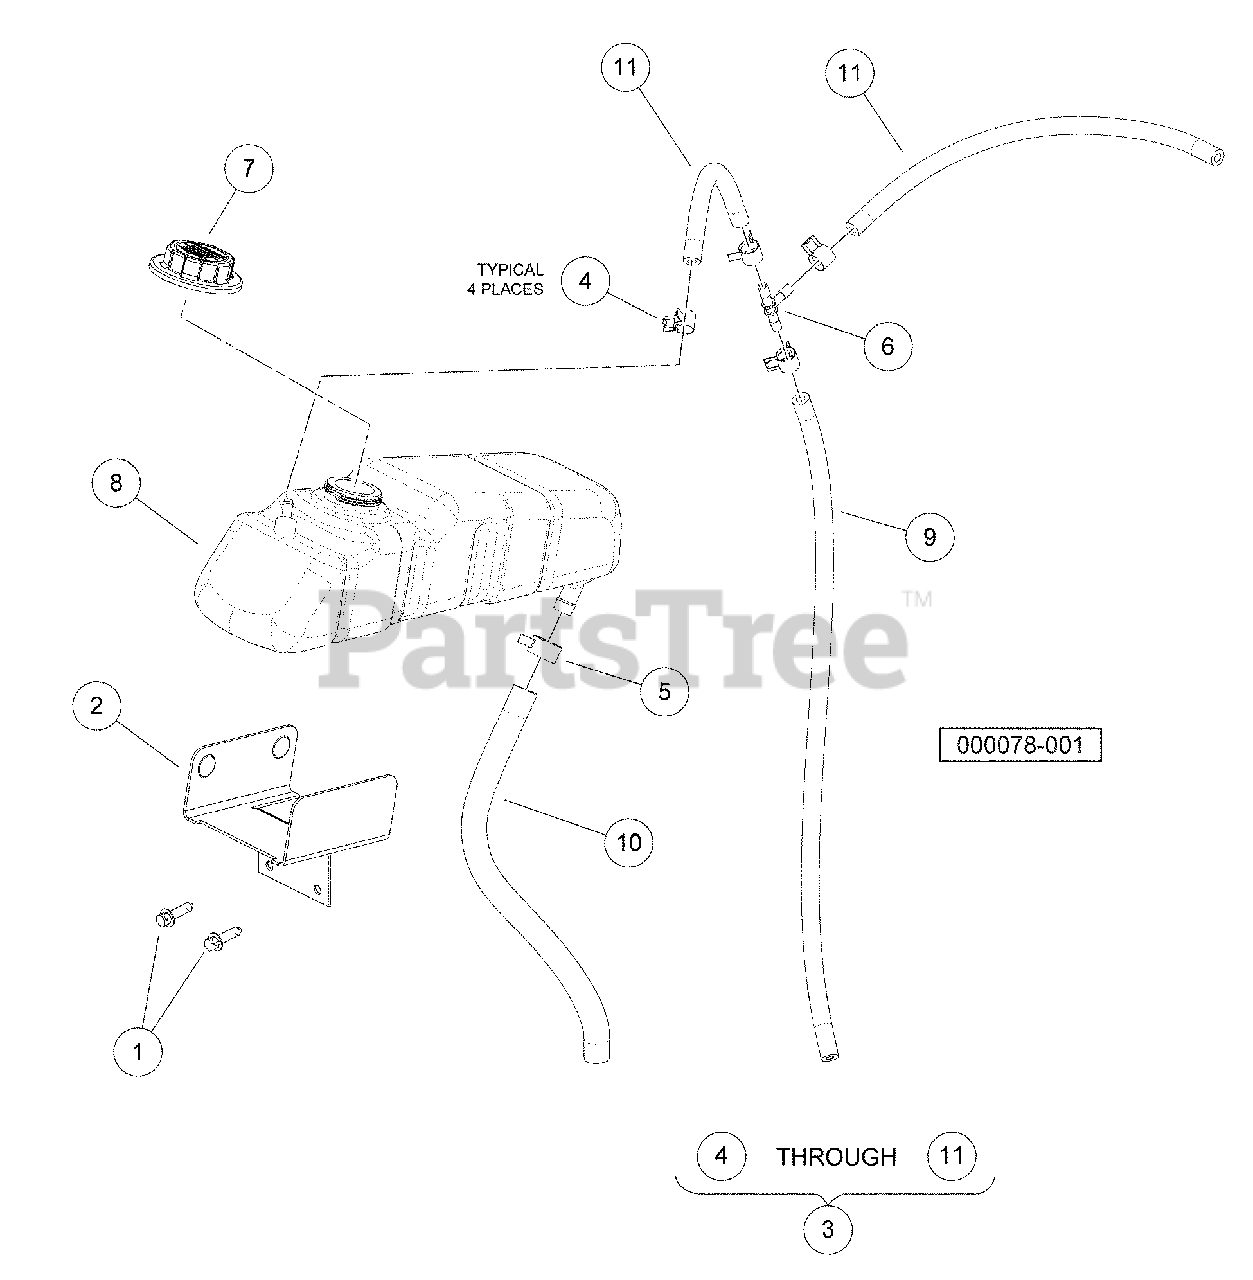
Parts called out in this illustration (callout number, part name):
1	Screw, M8X1.25X30, Hex
2	Bracket, Coolant Bottle
3	Asm, Tank, Expansion
4	Clamp, Hose, CTB 15mm
5	Clamp, Hose, CTB 22mm
6	Fitting, Tee
7	Cap, Radiator
8	Tank, Expansion.
9	Hose, Tee To Vent Tube, Coolnt
10	Hose, Clnt, 5/8 Sae J20r3 Bulk
11	Hose, Clnt 5/16 Sae J20r3 Bulk
